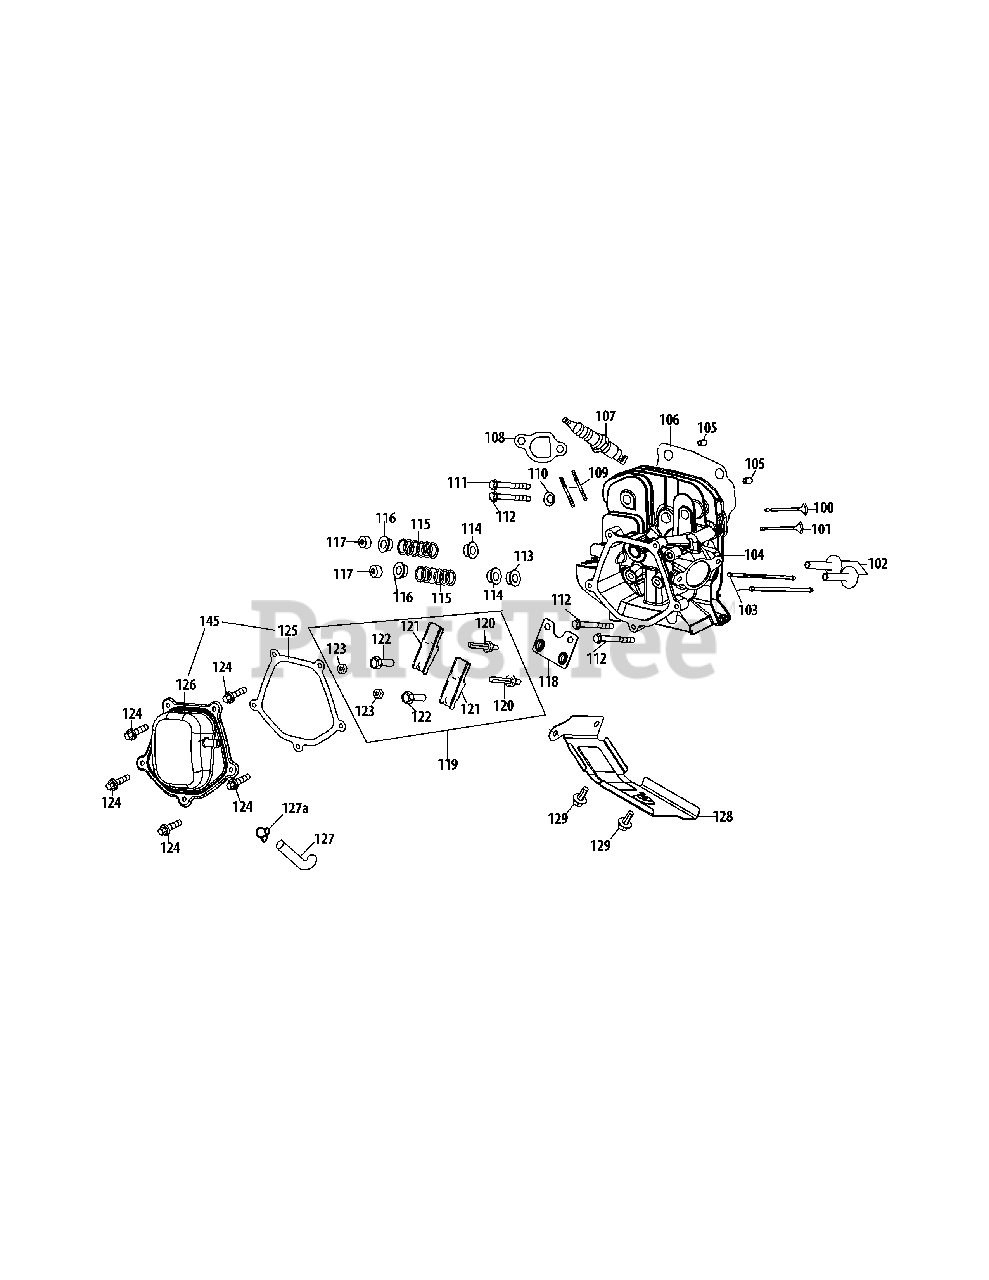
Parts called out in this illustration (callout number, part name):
102	Tappet
103	Push Rod Kit
104	Cylinder Head Kit
105	Dowel Pin 12×20
106	Gasket, Cylinder Head
107	Spark Plug/F6Rtc
108	Exhaust Pipe Gasket
109	Stud M8×48.5
109	Muffler Stud Assembly
110	Dish Flexibility Washer
111	Bolt M10×1.25×65
112	Bolt M10×1.25×87
113	Intake Valve Seal
114	Valve Spring Retainer
115	Valve Spring
116	Retainer, Ex.Valve Spring
117	Adjuster, Exh Valve
118	Push Rod Guide
119	Rocker Arm Assembly
120	Bolt, Pivot
121	Rocker Arm
122	Adjusting Nut ,Valve
123	Nut, Pivot Locking
124	Valve Cover Bolt
125	Valve Cover Gasket
126	Valve Cover
127	Breather Hose
128	Air Shield
129	Bolt M6×12
145	Valve Cover Kit
